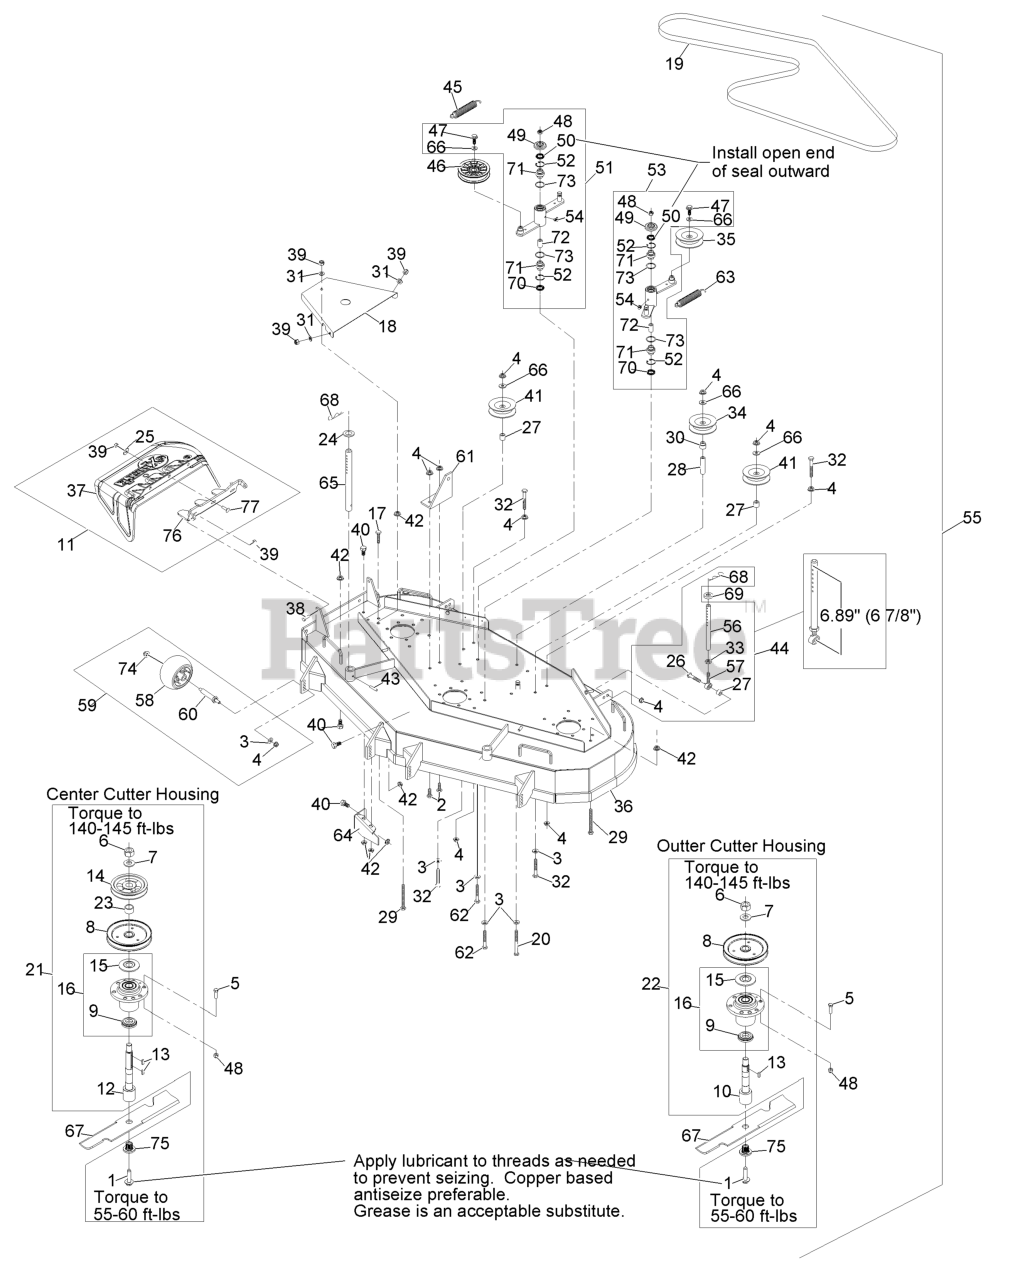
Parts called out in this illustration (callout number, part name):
2	SCREW-HH
3	WASHER-BELLEVILLE
4	NUT-HHF, WHIZ
5	SCREW-HH
8	SHEAVE,BLADE DRIVE 6.30
9	SPACER-GUARD, BOTTOM
10	KIT, SPLINED SPINDLE 103-
11	ASM,FMD DISCHARGE CHUTE
12	KIT, SPLINED SPINDLE 103-
14	SHEAVE,MOWER DRIVE
15	GUARD-BEARING, TOP
16	KIT, CUTTER HOUSING
17	SCREW-HH
18	SHIELD,BELT SIDE FMD524
19	BELT,BLADE DRIVE FMD524
20	SCREW-HH
21	ASM,CUTTER HSG FMD524 CTR
22	ASM, CUTTER HSG COMPLETE
23	SPACER,TUBE
24	SPACER-DECK SUPPORT
25	WASHER-FLAT
26	SCREW-HH
28	SPACER-ANCHOR, CLUTCH
29	BOLT,TAP HH
30	BUSHING,IDLER
31	WASHER-FLAT
32	BOLT-CARR
33	NUT-HJ
34	PULLEY-IDLER
35	PULLEY-IDLER
36	ASM, DECK W/ DECALS FMD52
37	CHUTE,DISCHARGE
38	SCREW-HH
39	NUT-LOCK, NI
40	SCREW-HH
41	IDLER,PULLEY
44	KIT,SUPPORT LINK W/PIN
45	SPRING-EXTENSION
46	PULLEY-IDLER, FLAT
47	SCREW-HHF
48	NUT-LOCK, NI
49	GUARD-TOP
50	SEAL-LIP, SINGLE
51	KIT, IDLER ARM W/BEARINGS
52	RING-SNAP
53	KIT, IDLER ARM W/BEARINGS
54	FITTING-GREASE, 90 DEG
55	Asm, Complete Deck
56	LINK,SUPPORT
57	BALLJOINT
58	ROLLER-SCALP, ANTI
61	BRACKET,SPRING ANCHOR
62	SCREW-HH
63	SPRING-EXTENSION
64	BAFFLE,DISCHARGE
65	ROD,DECK SUPPORT
66	WASHER-FLAT
68	PIN,HAIR COTTER
70	SEAL-LIP, DOUBLE
71	BEARING-SPHERICAL
72	BUSHING-LEVER, LIFT
74	Nut-Nyloc 3/8-16 Flg
75	BUSHING,SPLINED
76	BRACKET, DISCHARGE CHUTE
77	SCREW-CARR
